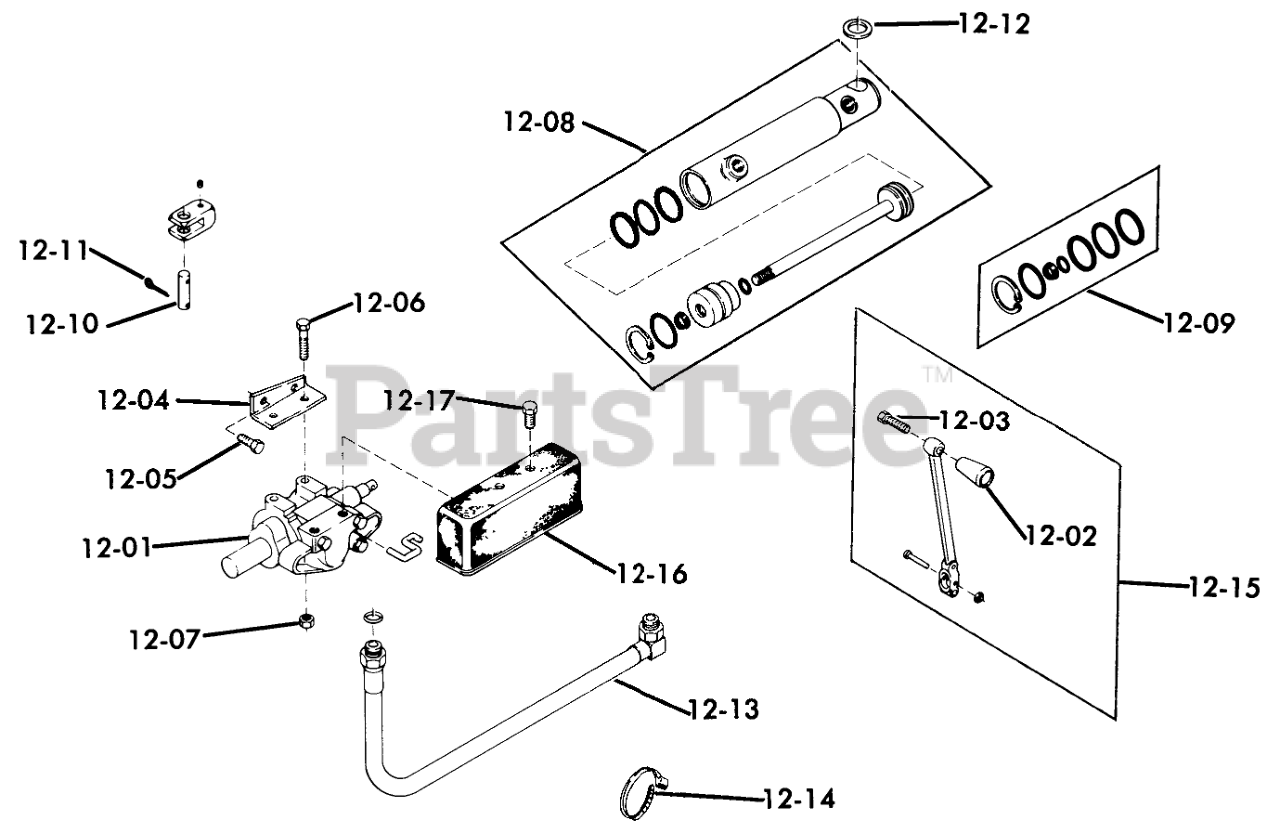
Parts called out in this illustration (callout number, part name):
12-01	Valve
12-01	Ring Kit
12-01	Spool Cap Kit
12-02	KNOB
12-03	SCREW
12-04	SUPPORT-VALVE
12-05	Bolt
12-06	Bolt 1/4-20 X 1 1/2
12-07	Nut
12-08	CYLINDER ASSY R
12-09	S/A O-RING&GASKET AS
12-10	PIN
12-12	Spacer
12-12	WASHER
12-13	16" Hose Assembly
12-13	HOSE HYDRAULIC 19"
12-13	ASSY-HYDRAULIC HOSE
12-13	HYD HOSE ASSY
12-14	PLASTIC TIE
12-15	Assy-Handle
12-16	Cover-Valve
12-17	Bolt
